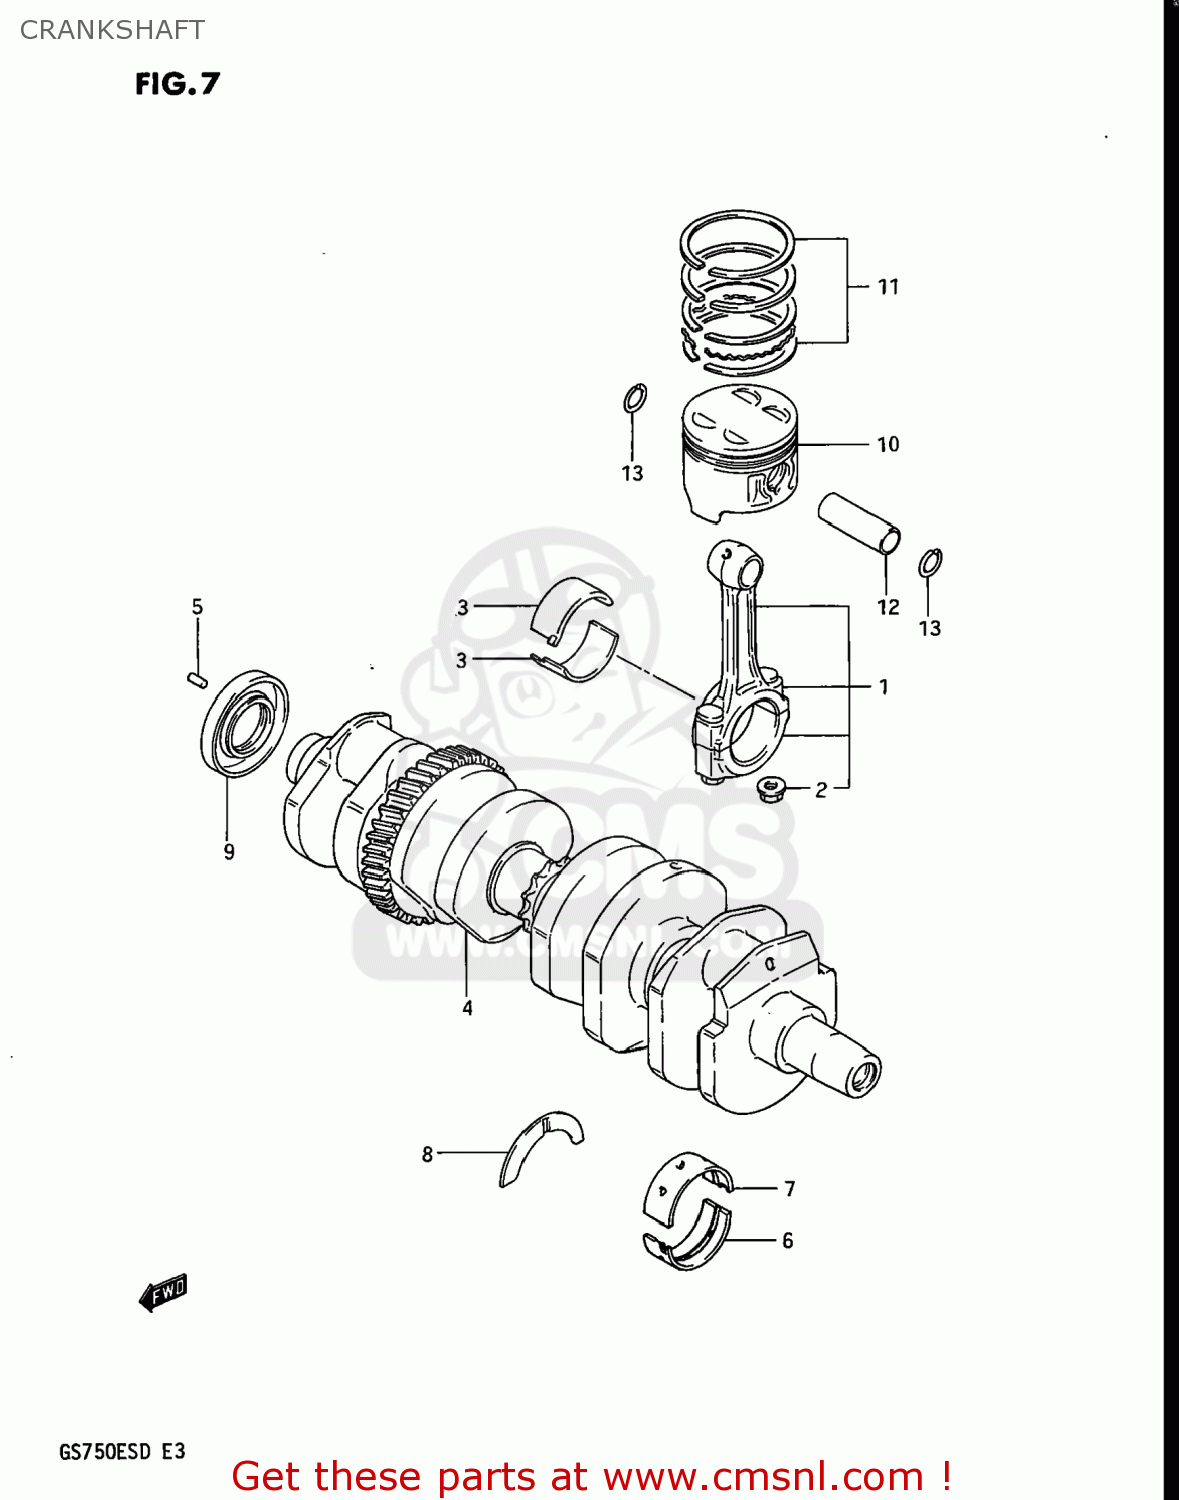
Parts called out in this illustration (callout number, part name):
1	ROD ASSEMBLY,CONNECTING
2	NUT
3	BEARING,CRANK PIN
4	CRANKSHAFT ASSEMBLY
5	PIN
6	METAL CRANKSHAFT (YELLOW)
7	METAL CRANKSHAFT (BROWN)
8	PLATE,CRANK THRUST
9	OIL SEAL
10	PISTON
11	RING SET,PISTON
12	PIN,PISTON
13	CIRCLIP
